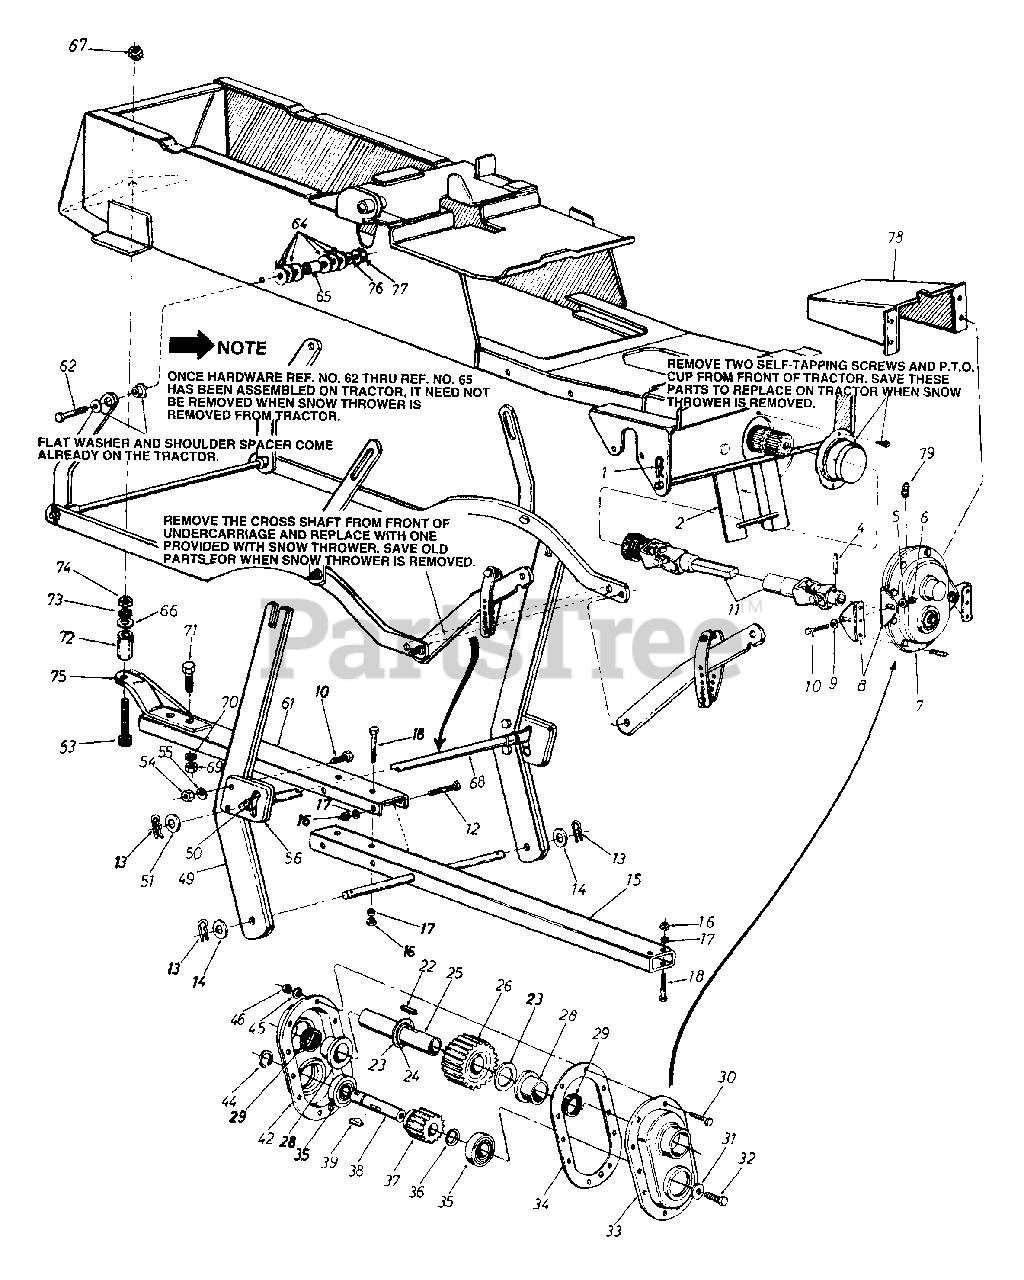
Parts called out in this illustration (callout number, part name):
1	Intern. Cotter Pin 3/4" Dia.
2	Guide Bracket Ass'y.
4	Spring Pin Spiral 5/16" Dia. x 2.5" Lg.
5	Bell-Wash. .341" I.D. x .88" O.D.
6	Hex Nut 5/16-18 Thd.
7	Gear Box Ass'y. Comp.
8	Gear Box Support Brkt.
9	Bell-Wash. .341" I.D. x .88" O.D.
10	Hex Bolt 5/26-18 x .75" Lg.
11	Universal Drive Shaft Ass'y.
12	Hex Bolt 3/8-24 x 4.5" Lg.
13	Hairpin Cotter
14	Fl-Wash. .62" I.D. x 1.12" O.D.
15	Lift Shaft Ass'y.
16	Hex Ins. Jam L-Nut 3/8-24 Thd.
17	L-Wash. 3/8" I.D.
18	Hex Bolt 3/8-24 x 2.75" Lg.
22	Fl-Wash. 1.31" I.D. x 2.0" O.D. x .060
24	Snap Ring for 1.25" Dia. Shaft
25	Gear Shaft 1.25" Dia. x 6.0" Lg.
26	28 Teeth Spur Gear
28	Flange Brg. 1.25" 1.0. x 1.75" 0 D.
29	Oil Seal 1.25" I.D. x 1.75" O.D. x .26"
30	Hex Bolt 1/4-28 x .88" Lg.
31	Fl-Wash. .40" I.D. x 1.25" O.D. x .160"
32	Hex L-Scr. 3/8-24 x 1.0" Lg.
33	Compl. Gear Hsg. Half - L.H.
35	Ball Brg. 1.0" I.D. x 2.0" O.D.
36	Fl-Wash. 1.03" I.D. x 1.63" x .090"
37	15 Teeth Spur Gear
39	Woodruff Key 1/4" x 3/4" Dia.
42	Compl. Gear Hsg. Half - R.H.
44	Snap Ring for 1.0" Dia. Shaft
45	Spring Wash. 1/4" I.D.
46	Hex Nut 1/4-28 Thd.
51	Fl-Wash. .62" I.D. x 1.12" O.D.
53	Hex Bolt 5/8-18 x 4.0" Lg.
54	Hex Nut 5/16-18 Thd.
55	L-Wash. 5/16" I.D.
59	Hex Bolt 3/8-24 x 2.75"
61	Lift Bracket
62	Hex Bolt 3/8-24 x 2.5" Lg.
64	Fl-Wash. .375" I.D. x 1.0" O.D. x .135"
65	Spacer .275" I.D. x .625" O.D. x .440"
66	Fl-Wash. .62" I.D. x 1.12" O.D.
67	Hex Jam L-Nut 5/8-18 Thd.
68	Cross Shaft Ass'y.
70	L-Wash. 1/2" I.D.
71	Hex Bolt 1/2-13 x 1.25"
73	L-Wash. 5/8" I.D.
74	Hex Jam Nut 5/8-18 Thd.
77	Hex Nut 3/8-24 Thd.
